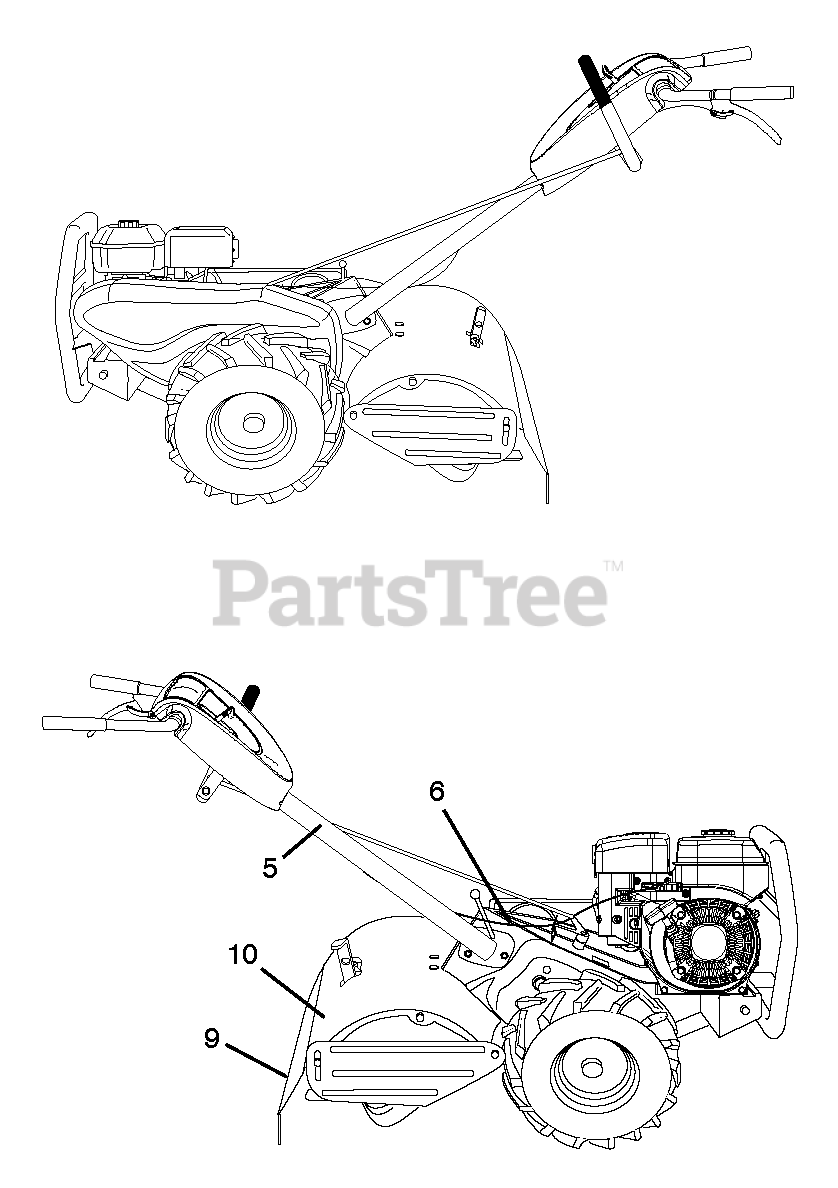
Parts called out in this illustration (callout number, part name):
5	DECAL.PLACEMENT.HAND.SYMBOLS
6	DECAL.SHIFT.INDICATOR.TILLER
9	DECAL.WARNING.4-SYM.TILLER.INT
10	DECAL EUROPE STANDARD CE
